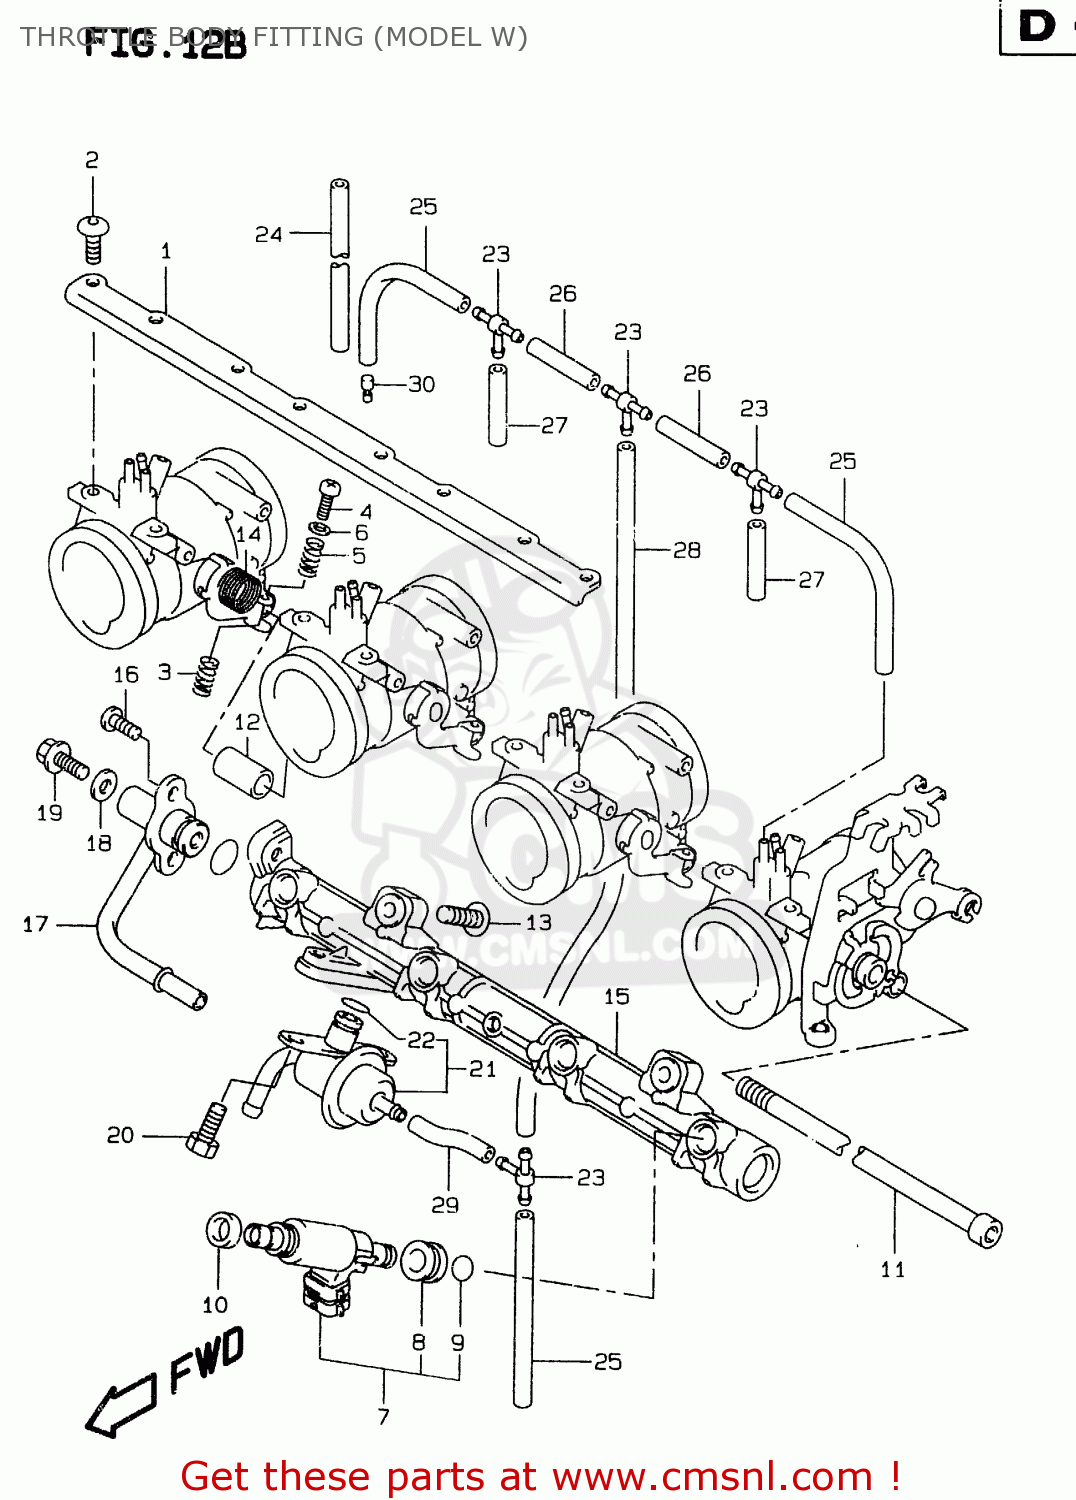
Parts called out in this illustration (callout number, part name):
1	PLATE
2	BOLT
3	SPRING,THROTTLE SCREW
4	SCREW
5	SPRING
6	WASHER
7	INJECTOR ASSEMBLY,FUEL
8	GROMMET
9	O RING
10	CUSHION,FUEL INJECTOR
11	BOLT
12	RING
13	BOLT
14	SPRING
15	DELIVERY PIPE
16	SCREW
17	NIPPLE
18	GASKET(5.8X13X1.2) (NAS)
19	UNION BOLT,AIR VENT
20	BOLT
21	REGULATOR COMP,FUEL
22	O RING
23	3 WAY
24	HOSE(3.5X7.5X600)
25	HOSE(3.5X7.5X600)
26	HOSE(3.5X7.5X600)
27	HOSE(3.5X7.5X600)
28	HOSE(3.5X7.5X600)
29	HOSE(3.5X7.5X600)
30	JET
